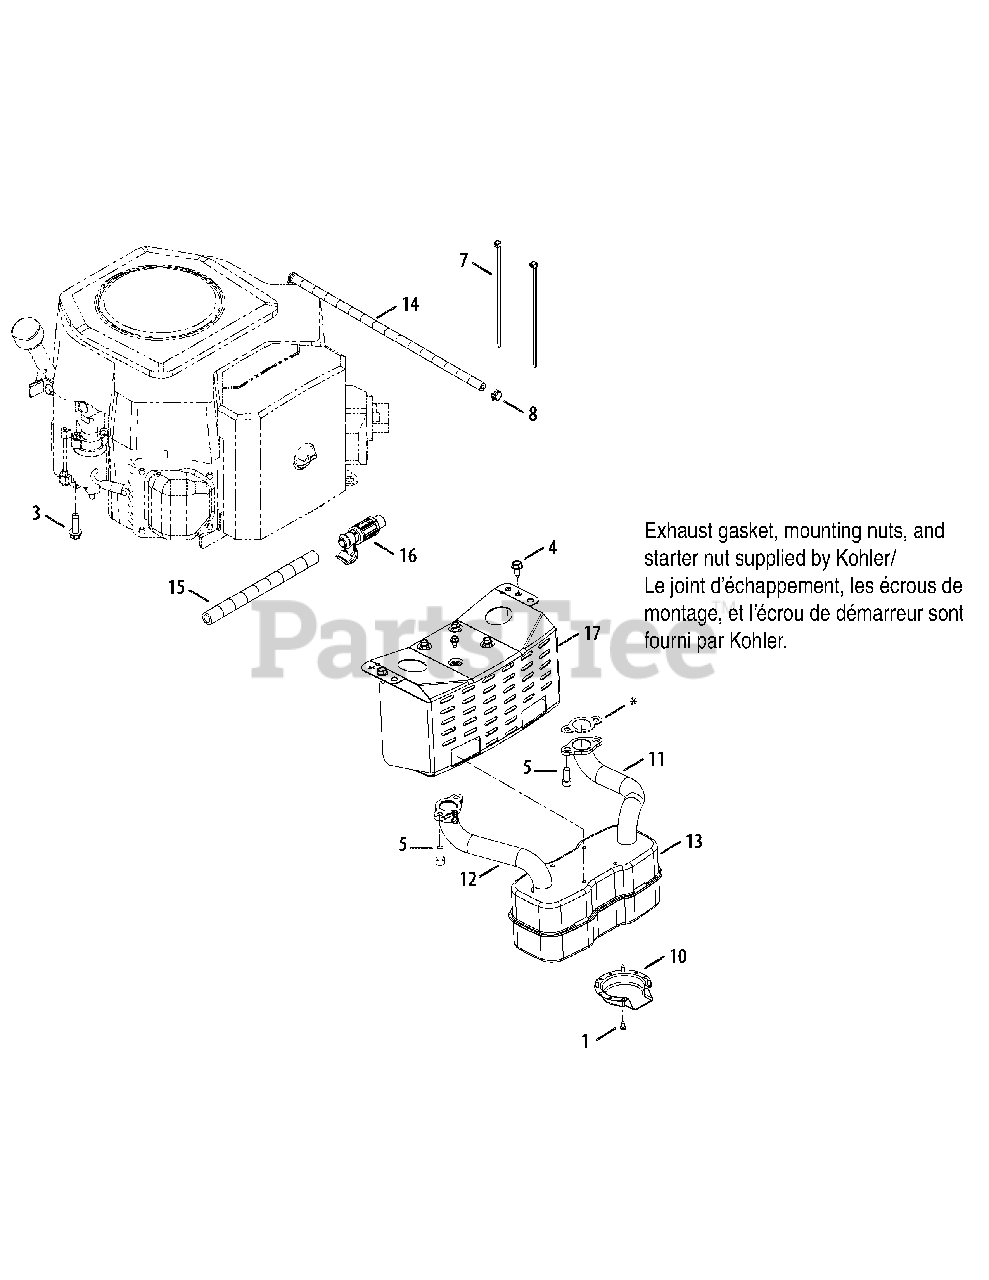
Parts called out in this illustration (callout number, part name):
1	Hex AB Scr #8-18 x .50
2	Hex Wash S-Tapp Scr 1/4-20 x .50
3	TT Screw 3/8-16 x 1.00
4	S-Tapp Scr 5/16-18 x .75
5	Scr. 5/16-18 x .75
6	Loctite 567 Sealant
10	Muffler Deflector
11	Exhaust Pipe LH
12	Exhaust Pipe RH
13	Muffler
14	Fuel Line
15	Oil Drain Hose
16	Oil Drain Cap
